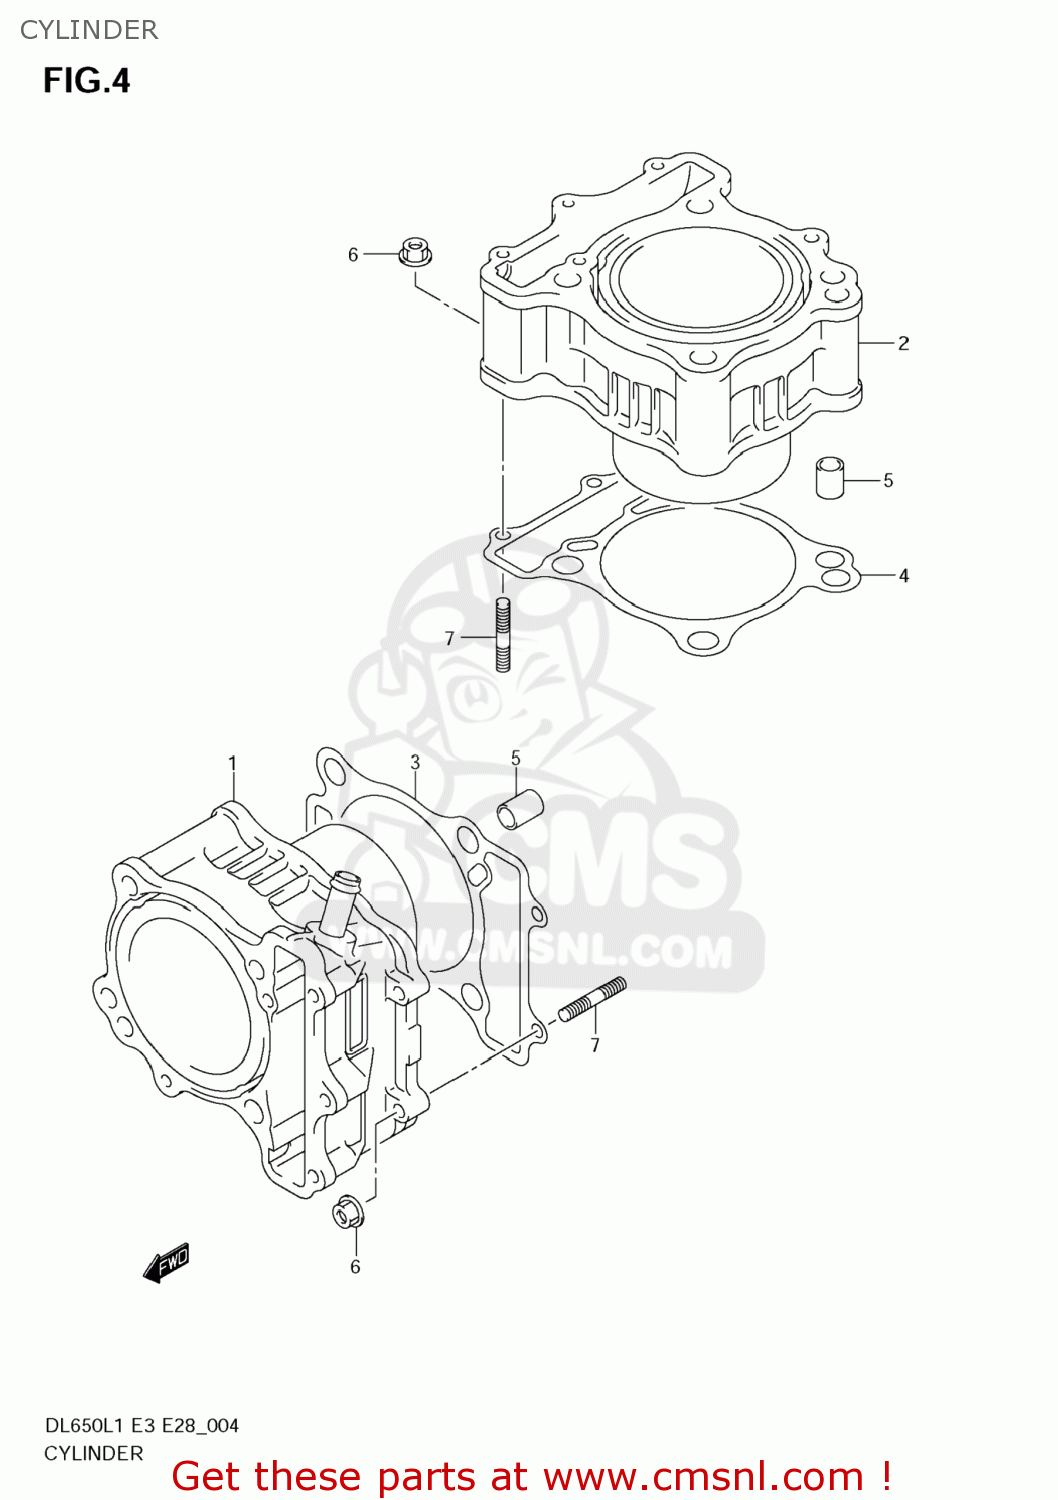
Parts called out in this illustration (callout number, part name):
1	CYLINDER,FR
2	CYLINDER,RR
3	GASKET,CYLINDER FR (NAS)
4	GASKET,CYLINDER RR (NAS)
5	PIN
6	NUT
7	BOLT,STUD
